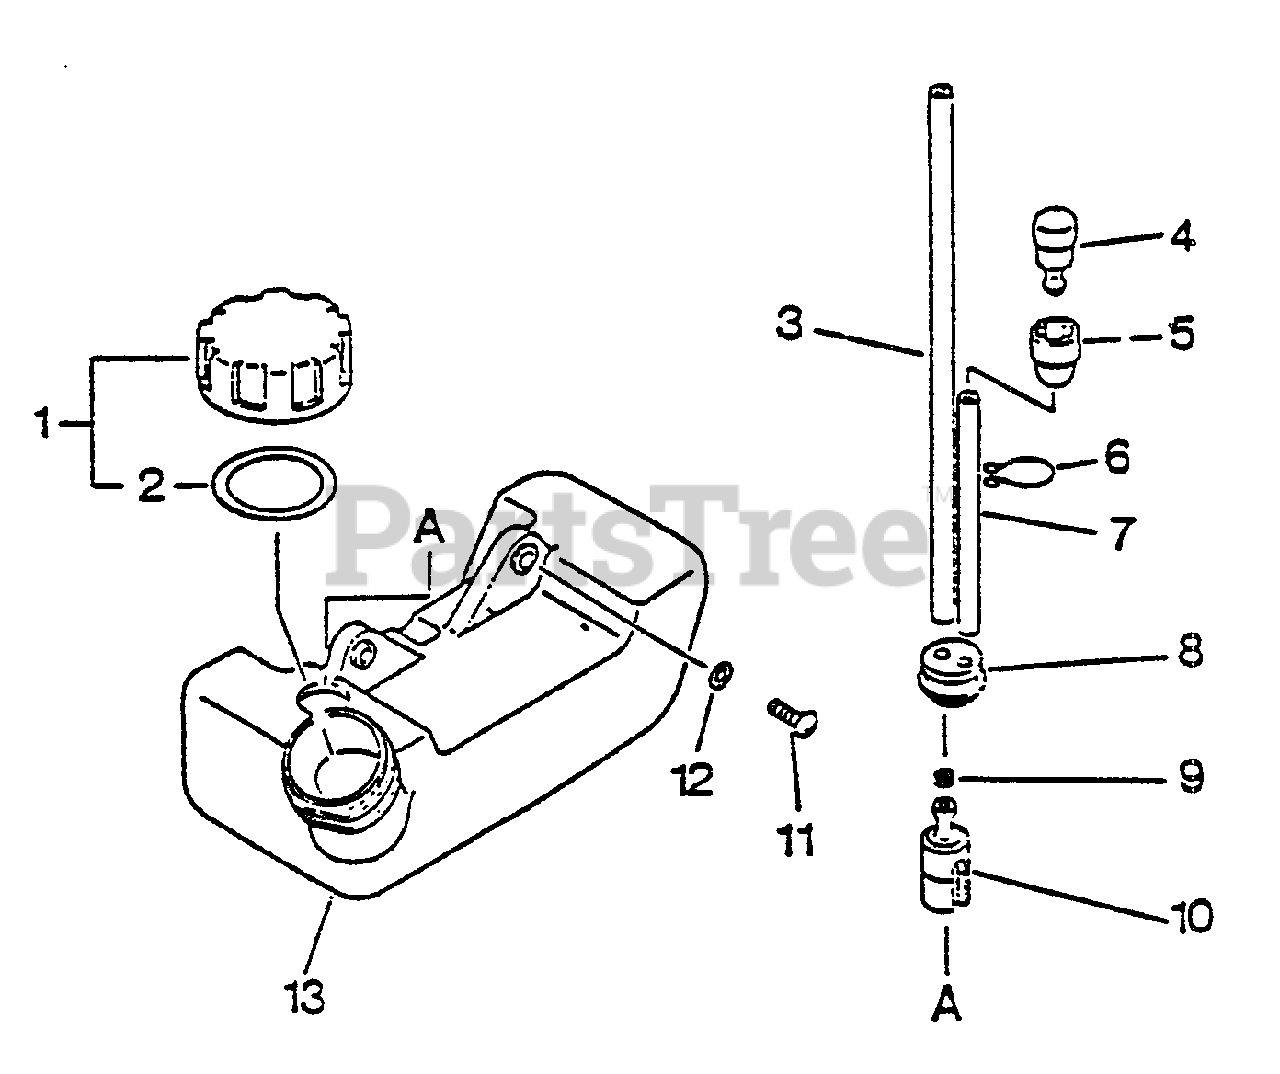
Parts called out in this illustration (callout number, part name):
1	CAP ASSY
2	GASKET, FUEL CAP
3	PIPE, FUEL 3x-5x-180
4	VENT ASSY
5	HOLDER, VENT
6	CLIP, TUBE
7	PIPE, FUEL RETURN 3×6×70
8	GROMMET, FUEL
9	CLIP 6 MM
10	FILTER, FUEL
11	SCREW 5×16
12	WASHER 5.5×12×0.8
13	TANK, FUEL
